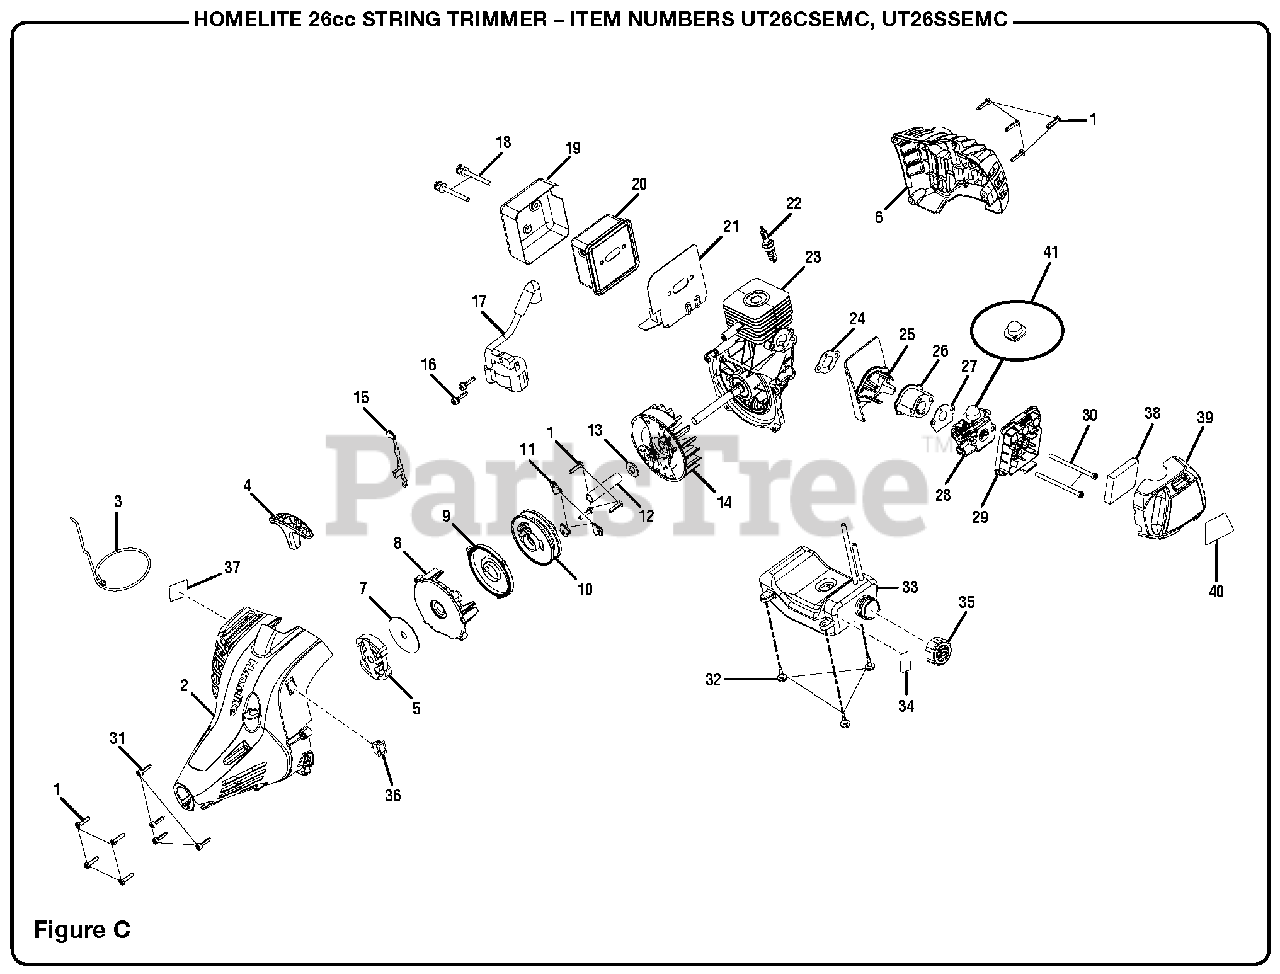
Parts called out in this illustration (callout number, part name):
1	Screw (M4 x 18 mm, T20 Torx Pan Hd.)
2	Starter Housing Assembly
3	Starter Rope (42 in.)
4	Pulley Handle
5	Clutch Assembly
6	Rear Housing
7	Clutch Washer
8	Starter Housing
9	Spring & Container Assembly
10	Starter Pulley Assembly
11	Pulley Retainer
13	Washer
14	Flywheel Assembly
15	Lead Assembly
16	Screw w/Washer (M4 x 19 mm, T20 Torx Pan Hd.)
17	Ignition Module
18	Screw w/Washers (10-24 x 2-1/8 in., T25 Torx Truss Hd.)
19	Heat Shield
20	Muffler Assembly
21	Muffler Gasket
22	Spark Plug (RCJ6Y)
23	Short Block Assembly
24	Intake Gasket
25	Heat Dam Deflector
27	Carburetor Gasket
28	Carburetor Assembly
29	Air Box Base
30	Screw (M5 x 76 mm, T20 Torx Truss Hd.)
31	Screw w/Washer (M4 x 16 mm, T25 Torx Truss Hd.)
32	Shoulder Screw w/Washer (M4 x 14 mm, T25 Torx Truss Hd.)
33	Fuel Tank w/Label & Cap Assembly
34	Gas Tank Warning Label
36	Momentary Stop Switch
37	Combustion Warning Label
38	Air Filter
39	Air Box Cover
40	Starting Label
